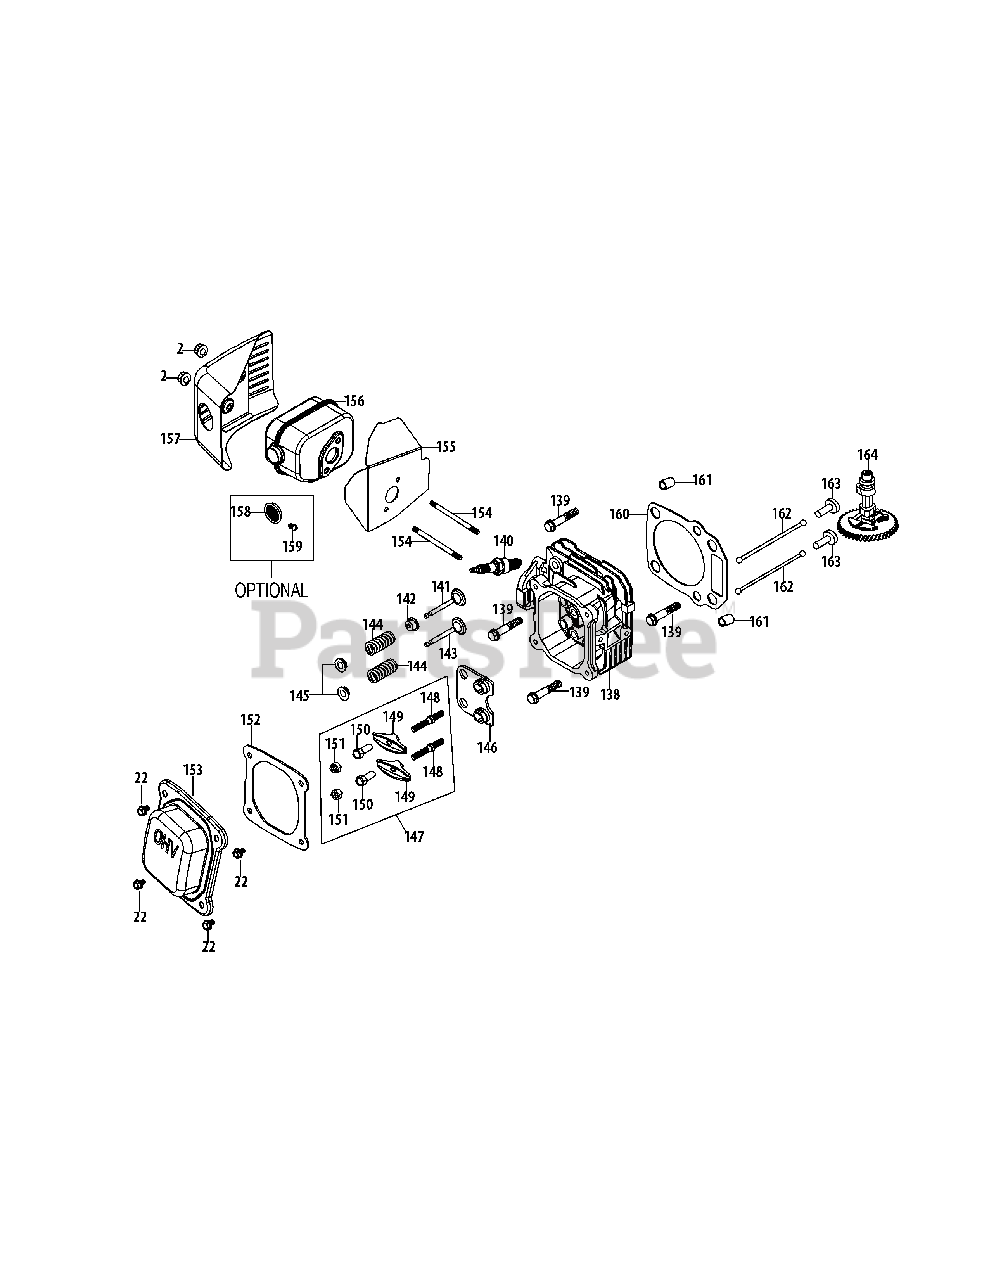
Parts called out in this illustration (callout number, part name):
2	Nut M6X10Mm Starter/Carb/Muffler
22	Bolt M6X14 Multi-Purpose
138	Cylinder Head Assembly
139	Bolt M8X54 Cylinder Head
140	Spark Plug
141	Valve Kit
142	Intake Valve Seal
143	Valve Kit
144	Valve Spring
145	Valve Spring Retainer
146	Push Rod Guide
147	Rocker Arm Assembly
148	Rocker Arm Stud
149	Rocker Arm
150	Fulcrum Nut
151	Jam Nut
152	Valve Cover Gasket
153	Valve Cover
154	Muffler Stud M6X95
154	Muffler Stud Assemlby
155	Muffler Gasket
156	Muffler Assembly
157	Muffler Shield
158	Spark Arrestor
159	Spark Arrestor Screw
160	Cylinder Head Gasket
161	Cylinder Head Dowel Pin 10×16
162	Push Rod Kit
163	Tappet
164	Camshaft Assembly
